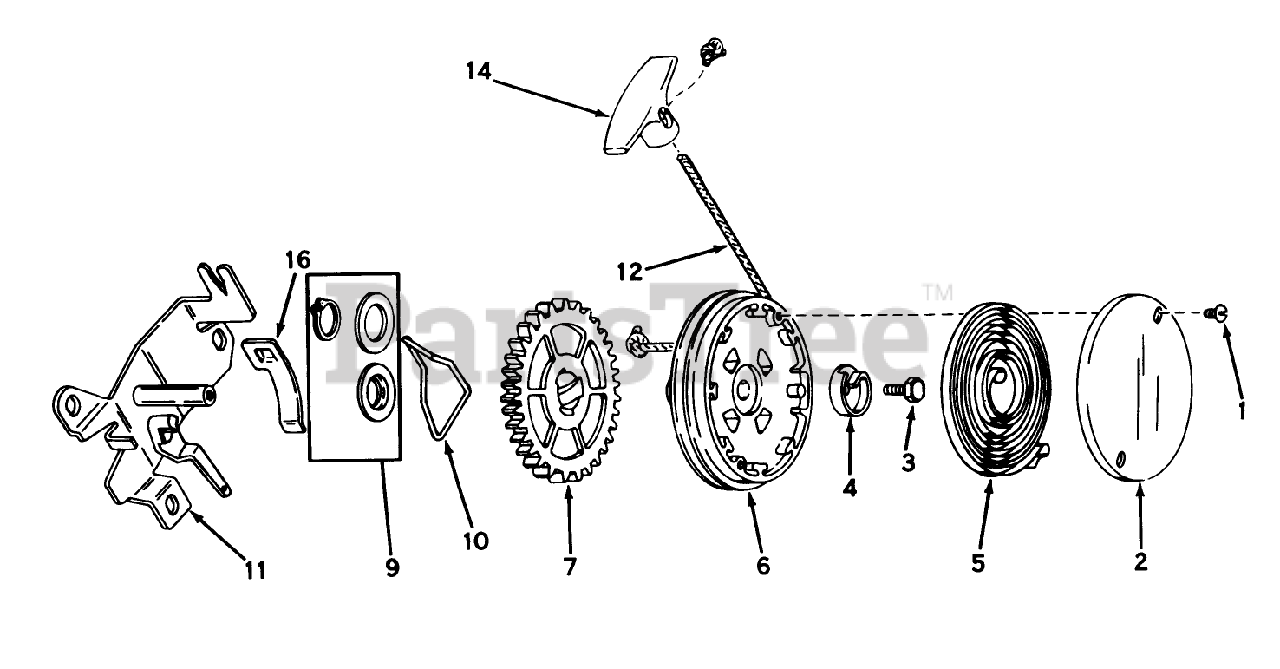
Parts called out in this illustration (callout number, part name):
2	Cover, Spring
3	Screw, Hex Washer Head
4	Hub Spring
5	Spring, Rewind
6	Pulley Assy. (Incl. Ref. #9)
9	Kit, Thrust Wash. & Snap Rg.
11	Bracket Assy., Mounting
12	Rope-Starter
14	Handle-Starter
16	Clip Rope
